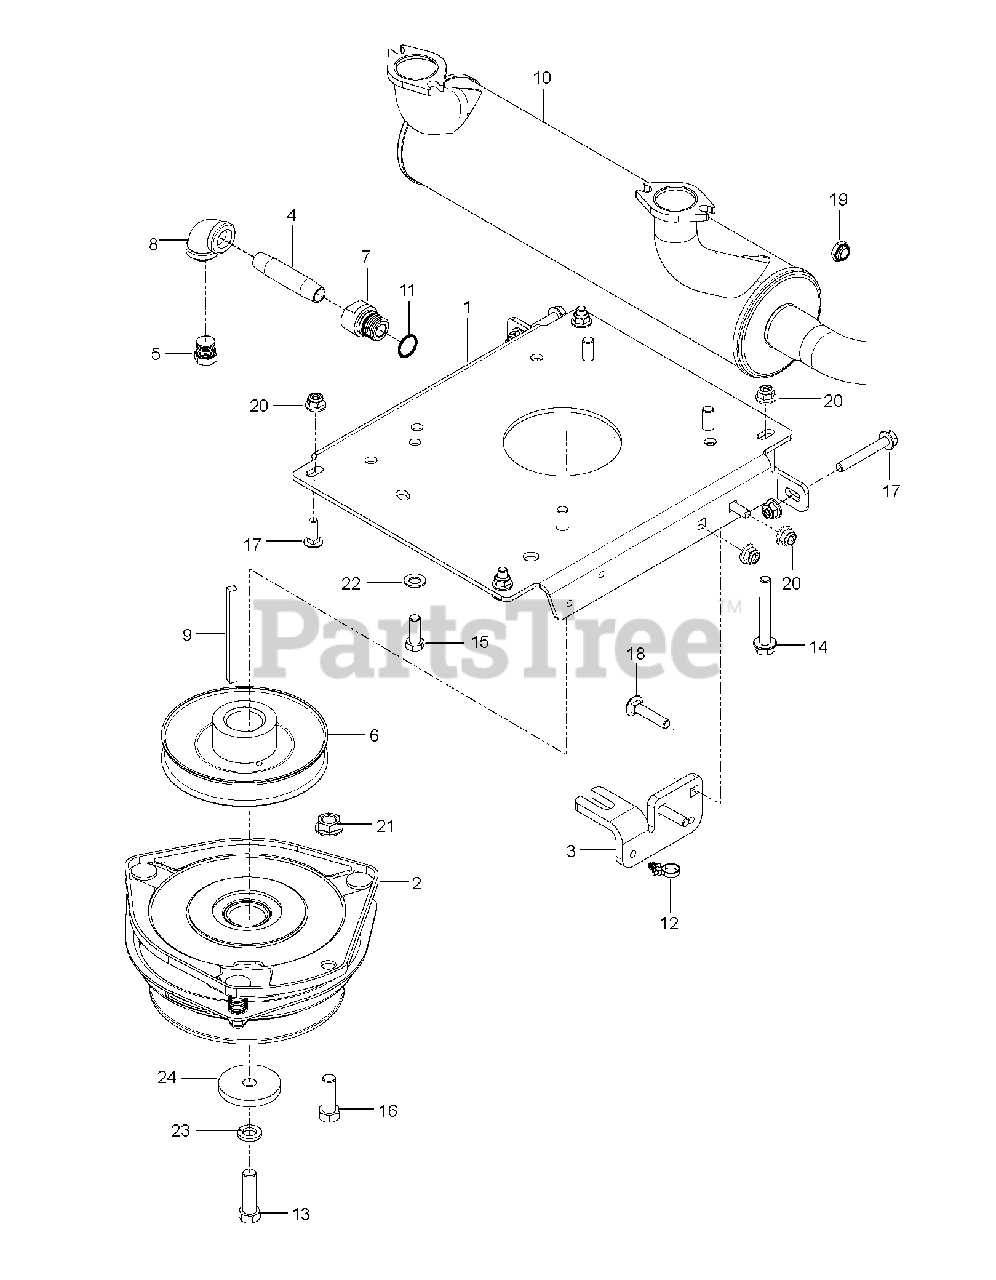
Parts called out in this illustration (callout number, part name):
1	PLATE.PNT.ENGINE.PZ/PZT.EDIP
2	CLUTCH, GT3.5
3	STOP, CLUTCH, OGURA
4	PIPE NIPPLE 3/8 X 3
5	PLUG, DRAIN 3/8 NPTF
6	PULLEY, ENGINE
7	ADAPTER, OIL DRAIN
8	90 DEG.ELBOW 3/8NPT
9	KEY, 1/4 SQ X 3.5
10	MUFFLER, 34HP KAW FX921V-1000V
12	TIE WRAP, 8-3/8", W/CLIP
13	CLUTCH BOLT7/16-20X1.5GR5.96HR
14	HHFS 5/16-18 X 2.25 GD 5
15	HCS 3/8-16X1.GRD.5.ZD
16	BOLT FIN HEX 7/16-14 X 1
17	RHSNB 5/16C X 1
18	RHSNB 5/16-18 X 1-1/2 GR 5 ZD
19	JAM NUT 1/4C (2 2 PW01)
20	5/16-18 NYLOC FLANGE NUT
21	NUT 7/16C WHIZ
22	WASHER, 3/8 DISC SPRING SPEC
23	WASHER 7/16 LOCK
24	BLADE WASHER
